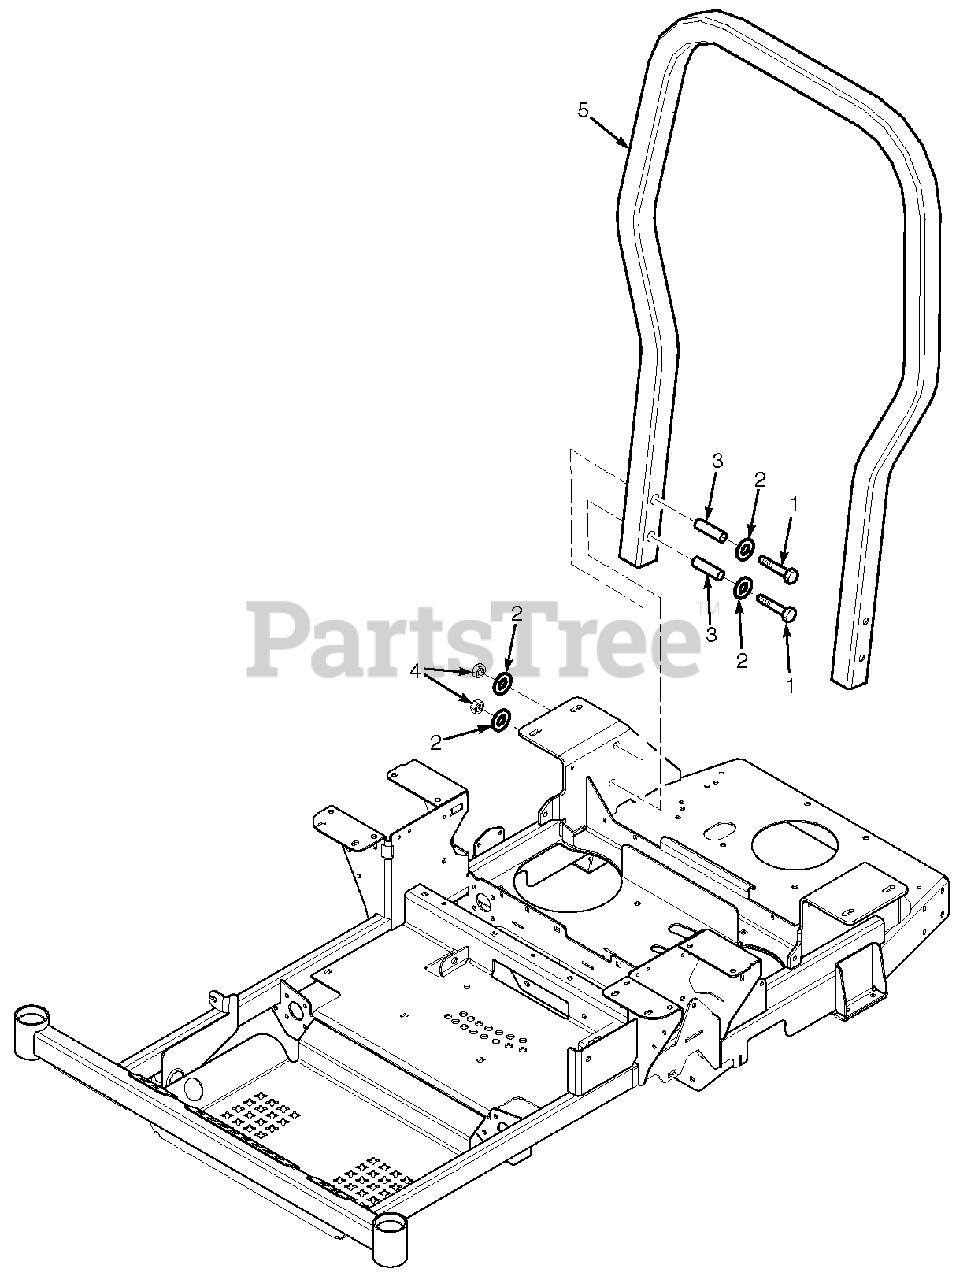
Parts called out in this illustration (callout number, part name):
1	Bolt, Hex Head 1/213 x 3-1/4" Gr. 8
2	Flatwasher, 1/2 - .531 x 1.062 x .095
3	Bushing, SFZ ROPS
4	Nut, Center Lock 1/2-13
5	ROPS, SFZ48, SFZ52
